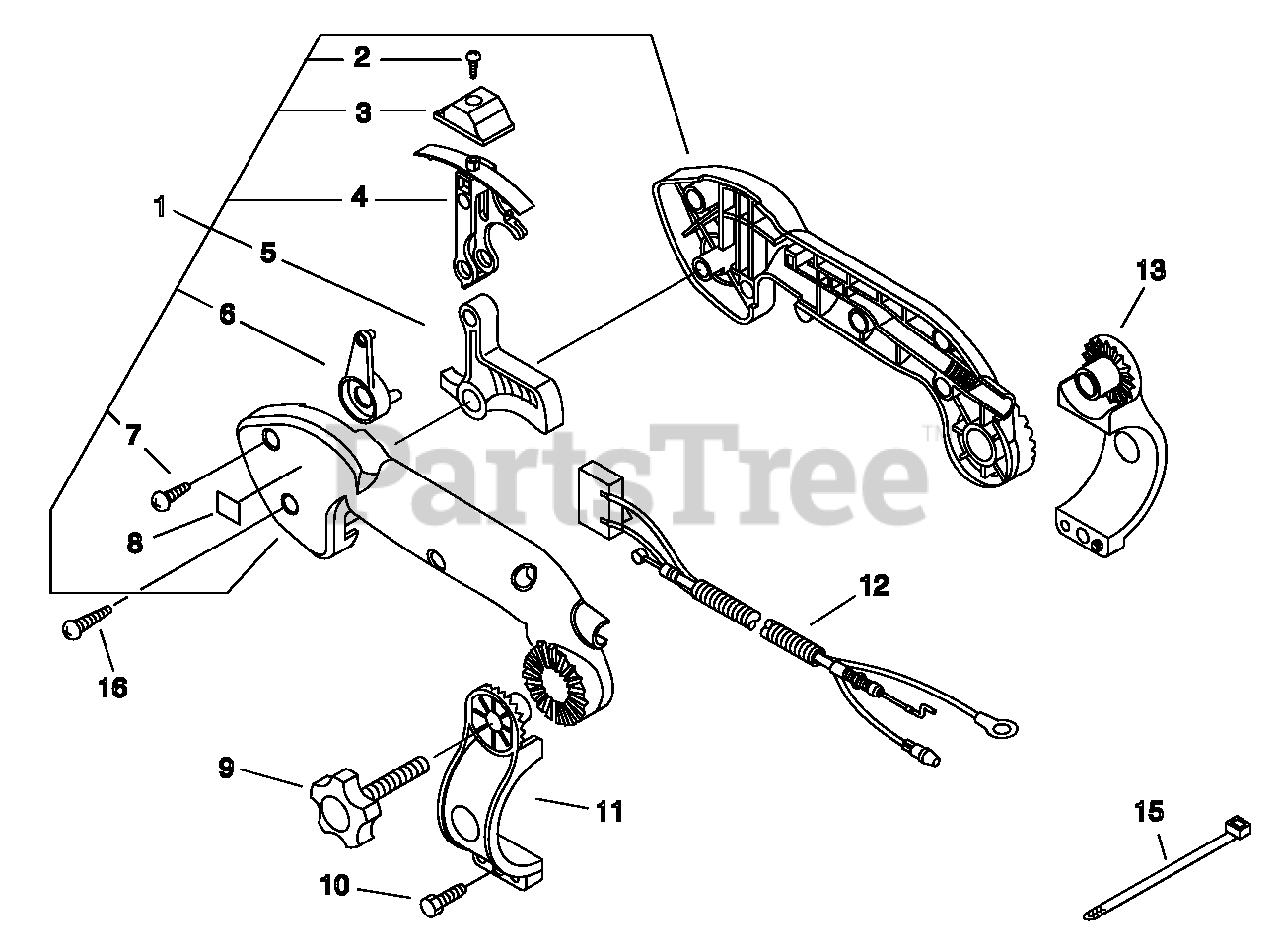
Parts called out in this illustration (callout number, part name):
1	CONTROL HANDLE ASSY
1	HANDLE ASSY, FRONT
2	SCREW 3×14
3	KNOB, CONTROL
4	CONTROL, THROTTLE
5	TRIGGER, THROTTLE
6	LEVER, THROTTLE
8	LABEL, CAUTION - IDLE
9	KNOB, SCREW
10	SCREW TAPPING 5×20
11	BRACKET, HANDLE - RIGHT
12	CABLE ASSY, CONTROL
13	BRACKET, HANDLE - LEFT
15	STRAP, TIE
